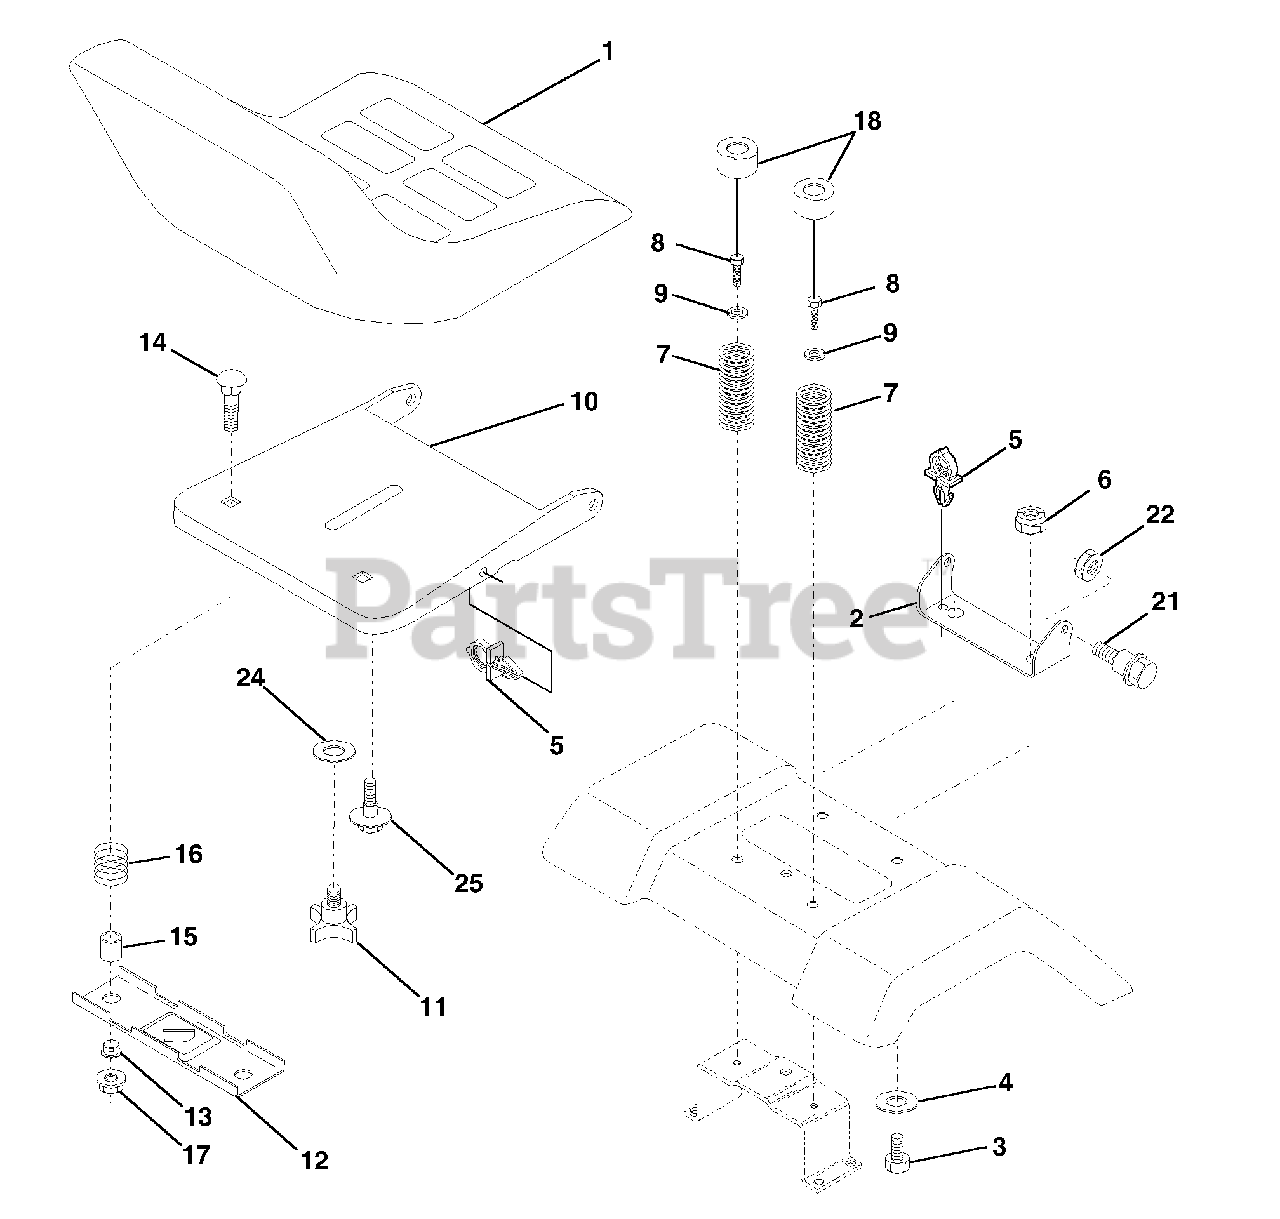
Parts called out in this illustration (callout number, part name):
1	Seat
2	Bracket Pivot Seat 8 720
3	Bolt Fin Hex 3/8-16unc X 1
4	Washer 13/32 X 1 X 10 Ga
5	Clip Push-In
6	Nut Hex w/Ins. 3/8-16 Unc
7	Spring Seat Cprsn 2 250 Blk Zi
8	Screw Thdrol 3/8-16 X 1 Ty-tt
9	Washer 13/32 X 1 X 14 Ga.
10	Pan Seat
11	Knob Seat 1/2-13 Unc Blk
12	Bracket Mounting Switch
13	Bushing Snap Blk Nyl 50 Id
14	Bolt Rdhd Sqnk 1/4-20x1-1/2
15	Spacer Split 28 x .88 Zinc
16	Spring Cprsn Plate
17	Nut Lock 1/4 Lge Flg Gr 5 Zinc
18	Cap Spring Seat
21	Bolt Shoulder 5/16-18 Unc
22	Nut Hex Lock W/Ins 5/16-18
24	Washer 17/32 X 1-3/16 X 12 Ga.
25	Bolt Shoulder 5/16-18 X 62
